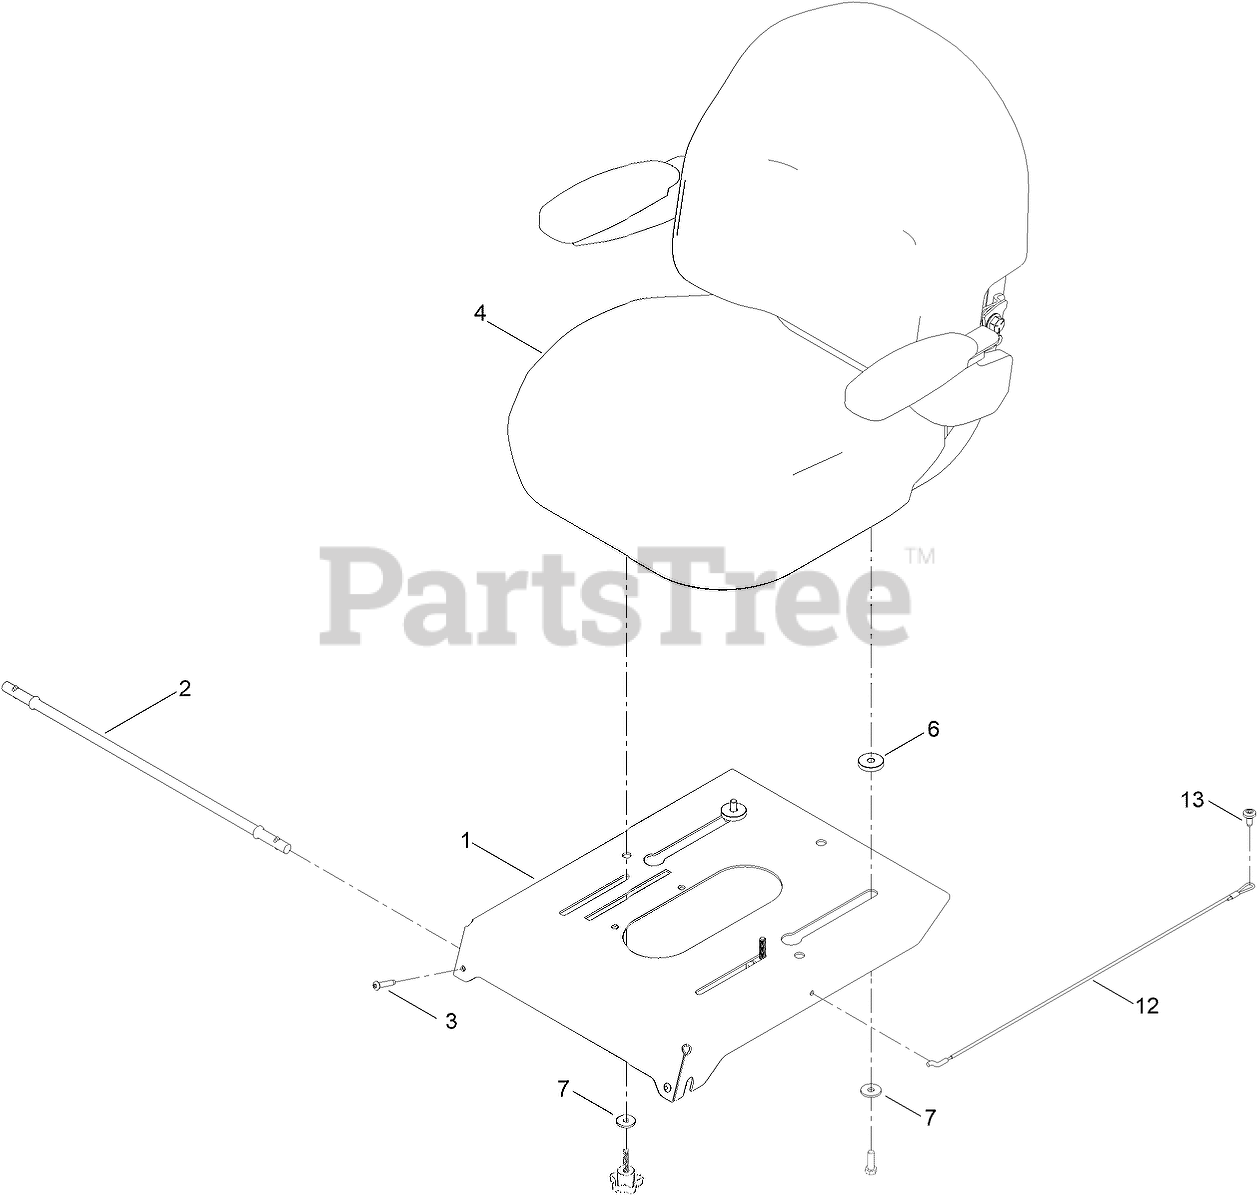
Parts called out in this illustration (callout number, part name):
1	PAN-SEAT, DELUXE
2	ROD-PIVOT
3	SCREW-TTH, THREAD ROLLING
4	SEAT ASM
6	SPACER-STEPPED
7	WASHER-FRICTION
12	CABLE-LANYARD
13	SCREW-SHOULDER
